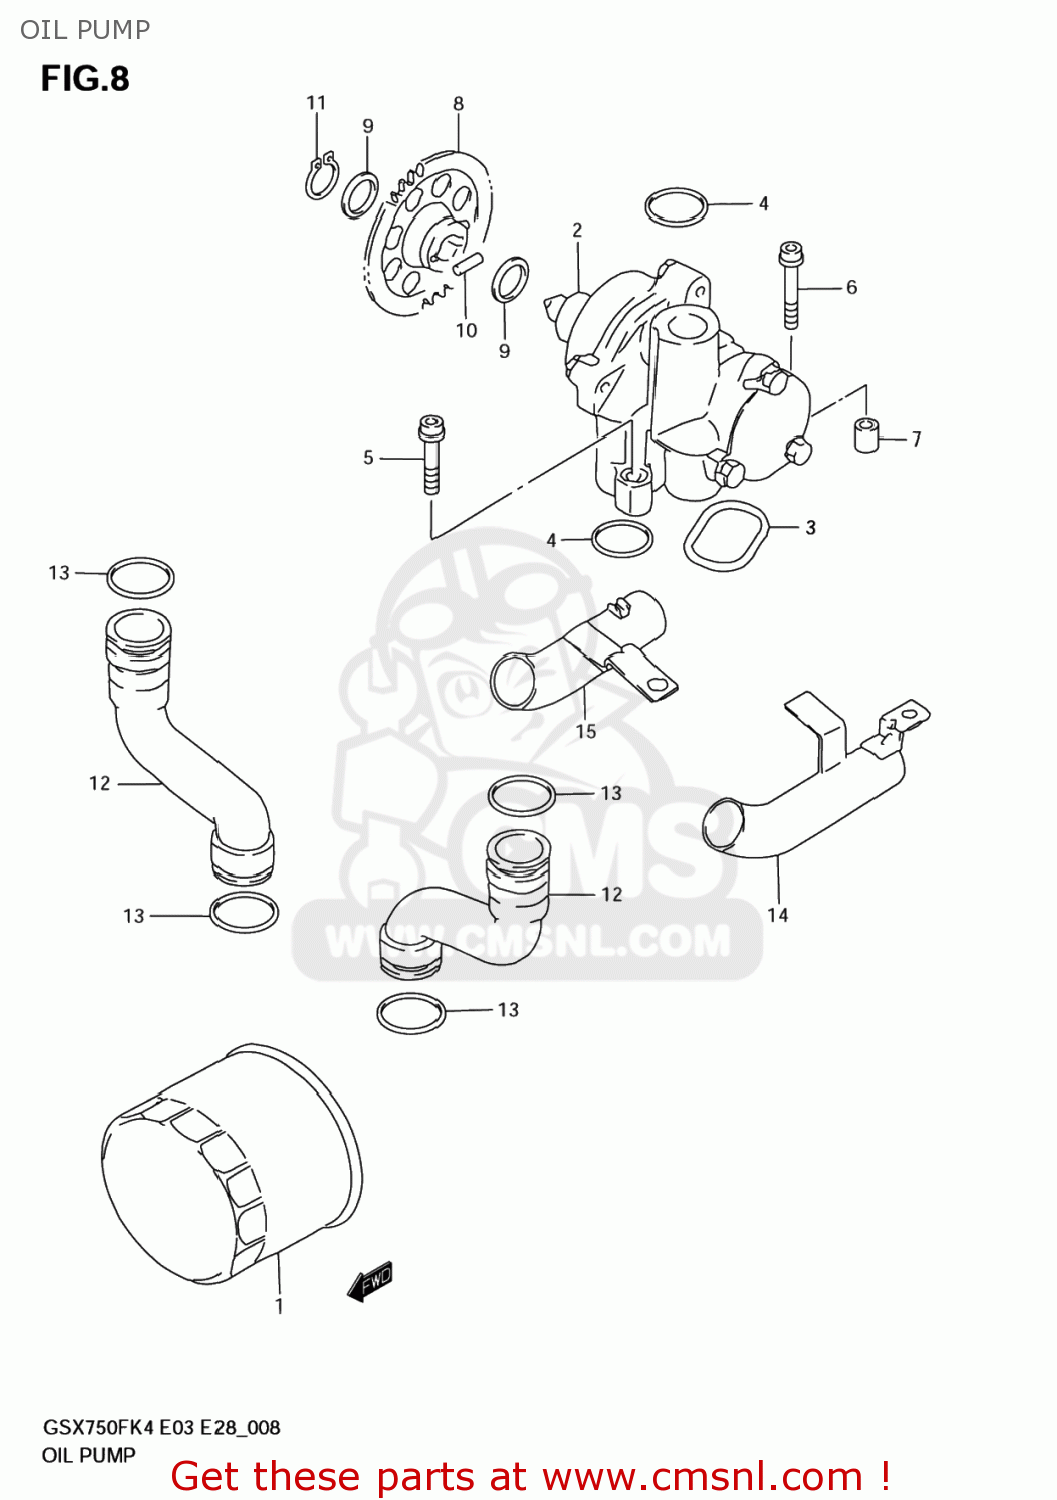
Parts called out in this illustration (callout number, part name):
1	FILTER ASSY,EN
2	PUMP ASSY,OIL
3	O RING,OIL PUMP
4	O RING(D:3.2,ID:17.8)
5	BOLT(6X30)
6	BOLT(6X35)
7	PIN
8	GEAR,OIL PUMP DRIVEN(NT:37)
9	SHIM
10	PIN(5X18)
11	CIRCLIP,12 MM
12	PIPE,OIL OUTLET
13	O RING(D:3.7,ID:21.7)
14	PIPE,OIL OUTLET UNDER,L
15	PIPE,OIL OUTLET UNDER,R
